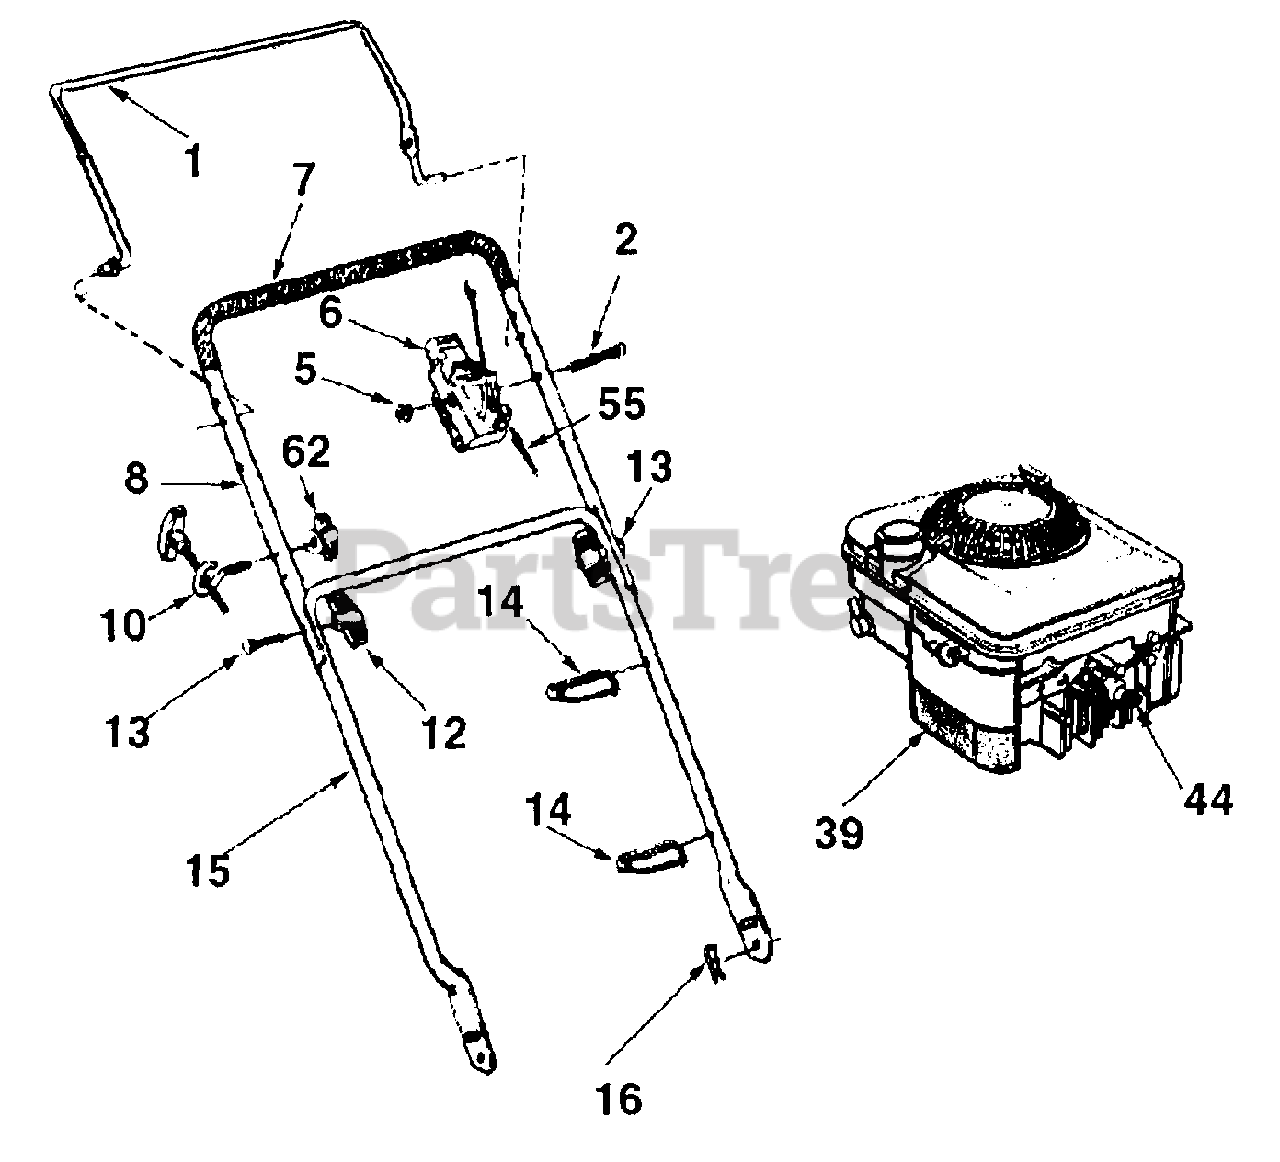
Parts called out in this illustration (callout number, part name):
2	Oval C-Sunk Screw
5	Hex Lock Nut
6	Control Housing
7	Foam Grip
12	Hand Knob
13	Carriage Bolt
14	Cable Tie
16	Hairpin Clip
39	Engine
44	Spark Plug Boot
55	Control Cable
62	Handle Knob
